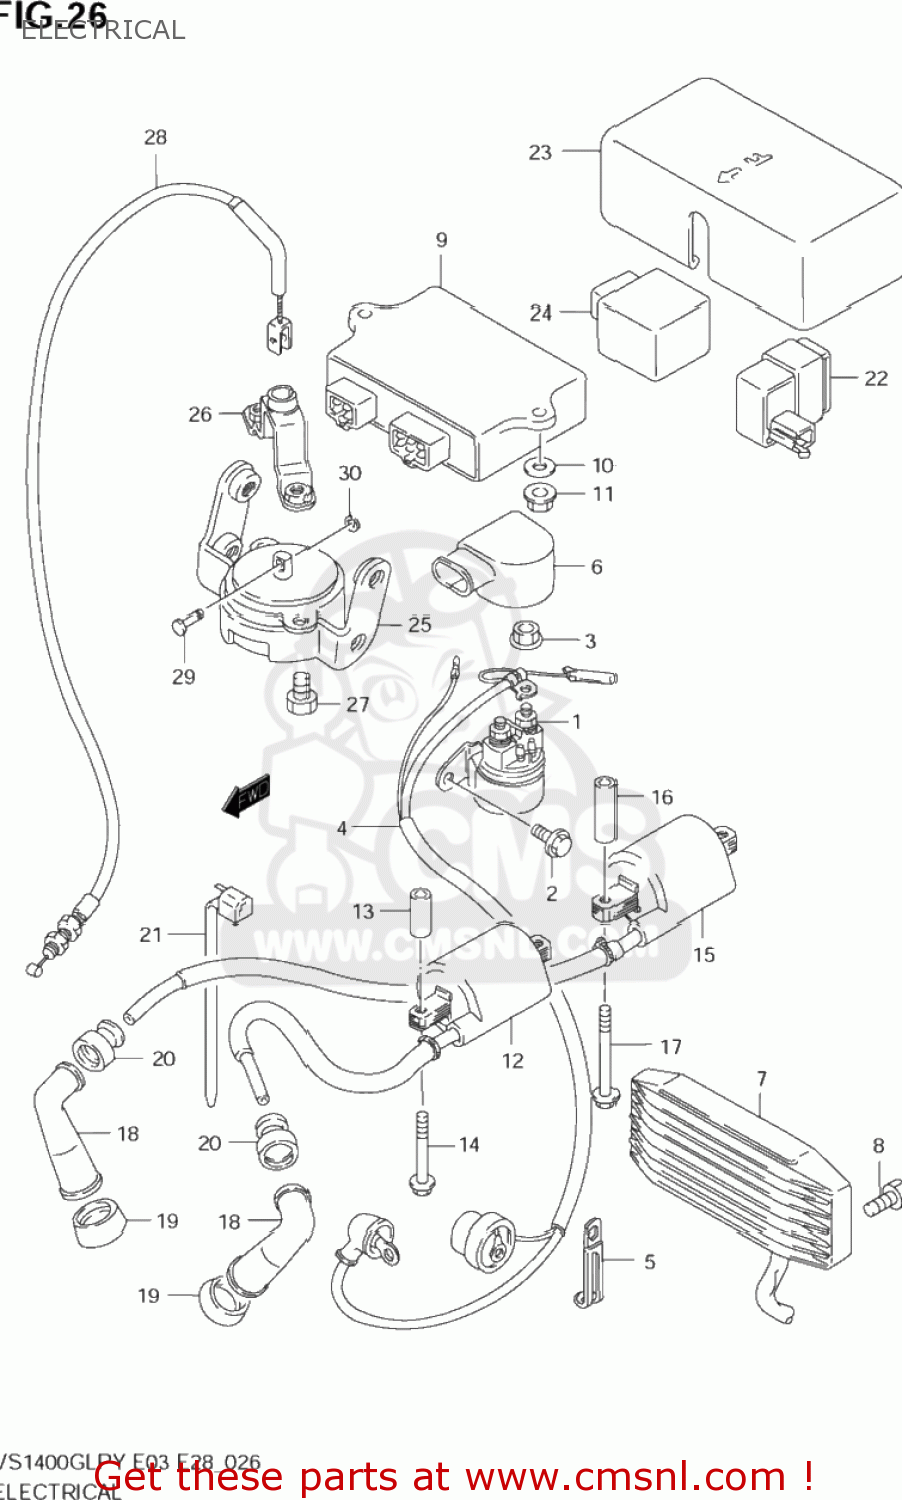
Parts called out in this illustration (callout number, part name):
1	RELAY ASSY,STARTING MOTOR
2	BOLT
3	NUT
4	WIRE,STARTER MOTOR LEAD
5	CLAMP L:35
6	CAP,STARTER RELAY TERMINAL
7	RECTIFIER ASSY
8	BOLT
9	IGNITOR ASSY
10	WASHER
11	NUT
12	COIL ASSY,IGNITION RR
13	SPACER(6.4X10X22)
14	BOLT
15	COIL ASSY,IGNITION
16	SPACER(6.4X10X32)
17	BOLT
18	CAP,SPARK PLUG
19	SEAL,SPARK PLUG CAP
20	SEAL,HIGH TENSION CORD
21	CLAMP(L:125)
22	RELAY ASSY,FUEL CUT
23	COVER,RELAY
24	CONTROL UNIT,DECOMP
25	SOLENOID ASSY,DECOMP
26	BRACKET,DECOMP SOLENOID
27	BOLT
28	CABLE ASSEMBLY,DECOMPRESSION
29	PIN(4X12.5)
30	E RING
